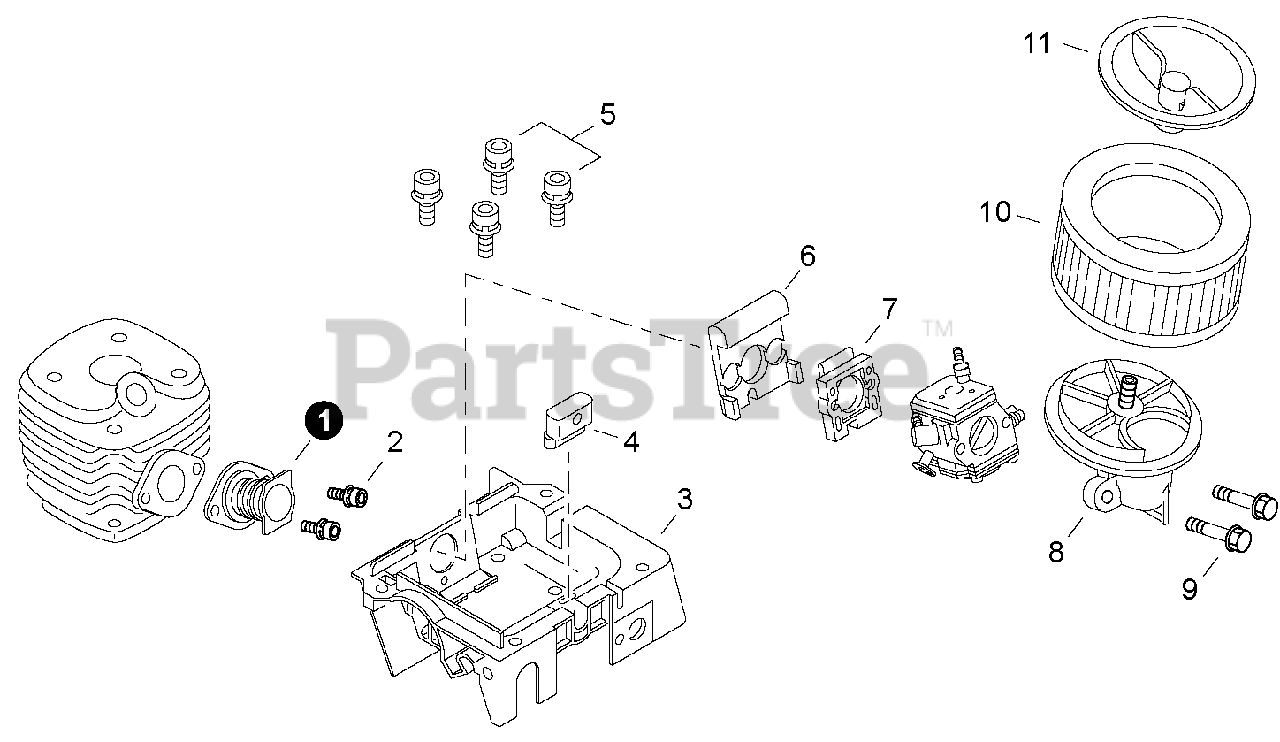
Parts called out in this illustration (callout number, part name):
1	BELLOWS, INTAKE
2	BOLT 5×14
3	CASE, CARBURETOR
4	CUSHION
5	BOLT 5×20
6	CUSHION
7	INSULATOR, INTAKE
8	MOUNT, AIR FILTER
9	BOLT, FLANGE
10	FILTER, AIR
11	COVER, AIR FILTER
